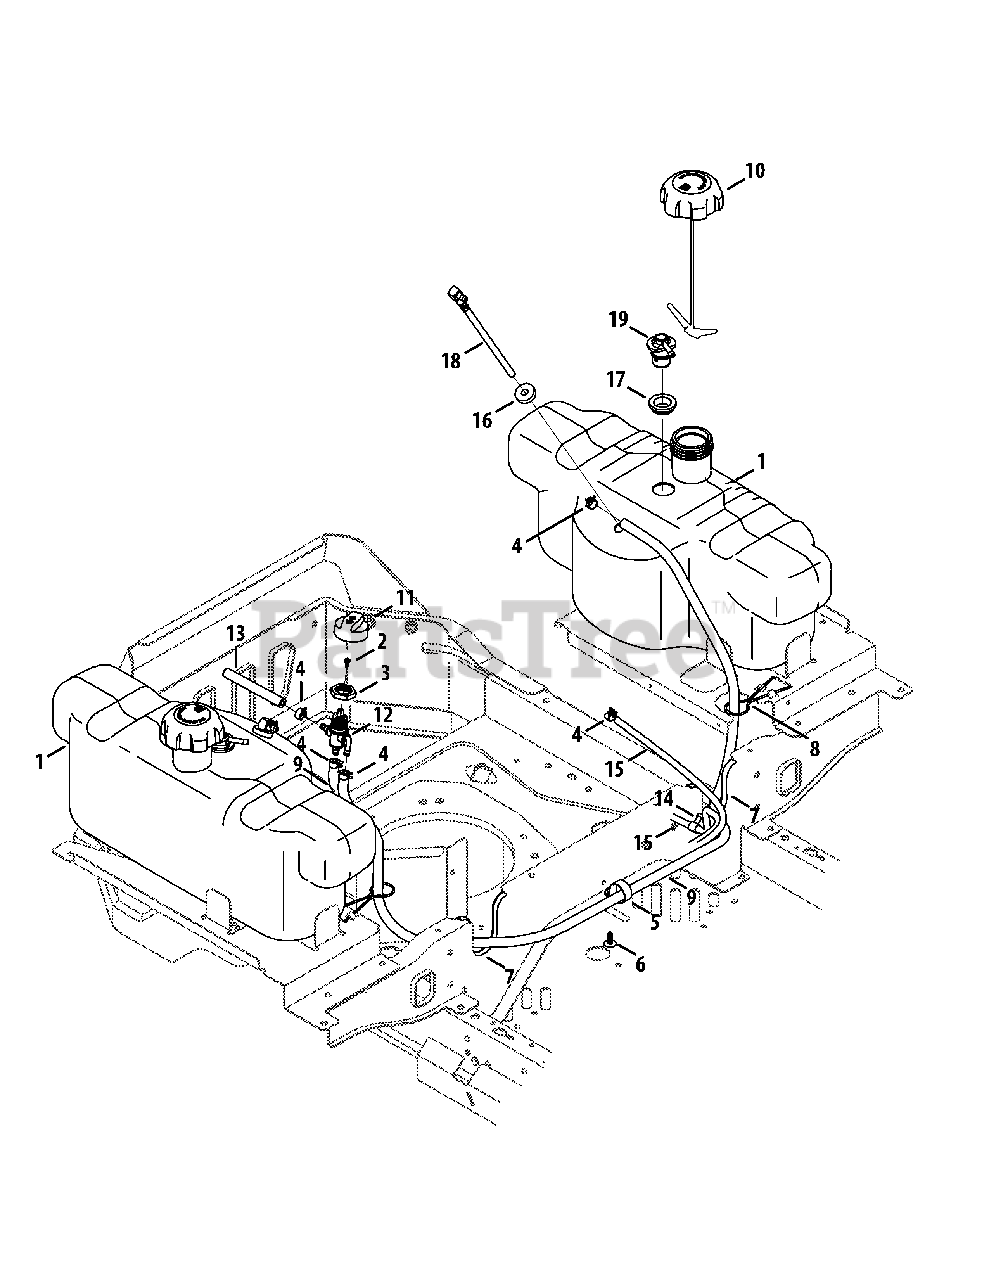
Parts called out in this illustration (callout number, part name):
1	Fuel Tank
2	Screw, M4-0.7 x 8mm
3	Nut, 3 Way Select
4	Hose Clamp, .490 Dia.
5	Hose Clamp, 1.0
6	Ratchet Clip, .250
7	Trim Strip
8	Tank Support Rod
9	Fuel Hose, Low Permeation, 1/4
10	Fuel Cap
11	Fuel Cap, 3 Way
12	Fuel Switch
13	Fuel Hose, Low Permeation, 1/4
14	Tee Fitting
16	Fuel Tank Bushing
17	Rubber Grommet
18	Fuel Pickup Fitting
19	Rollover Valve
